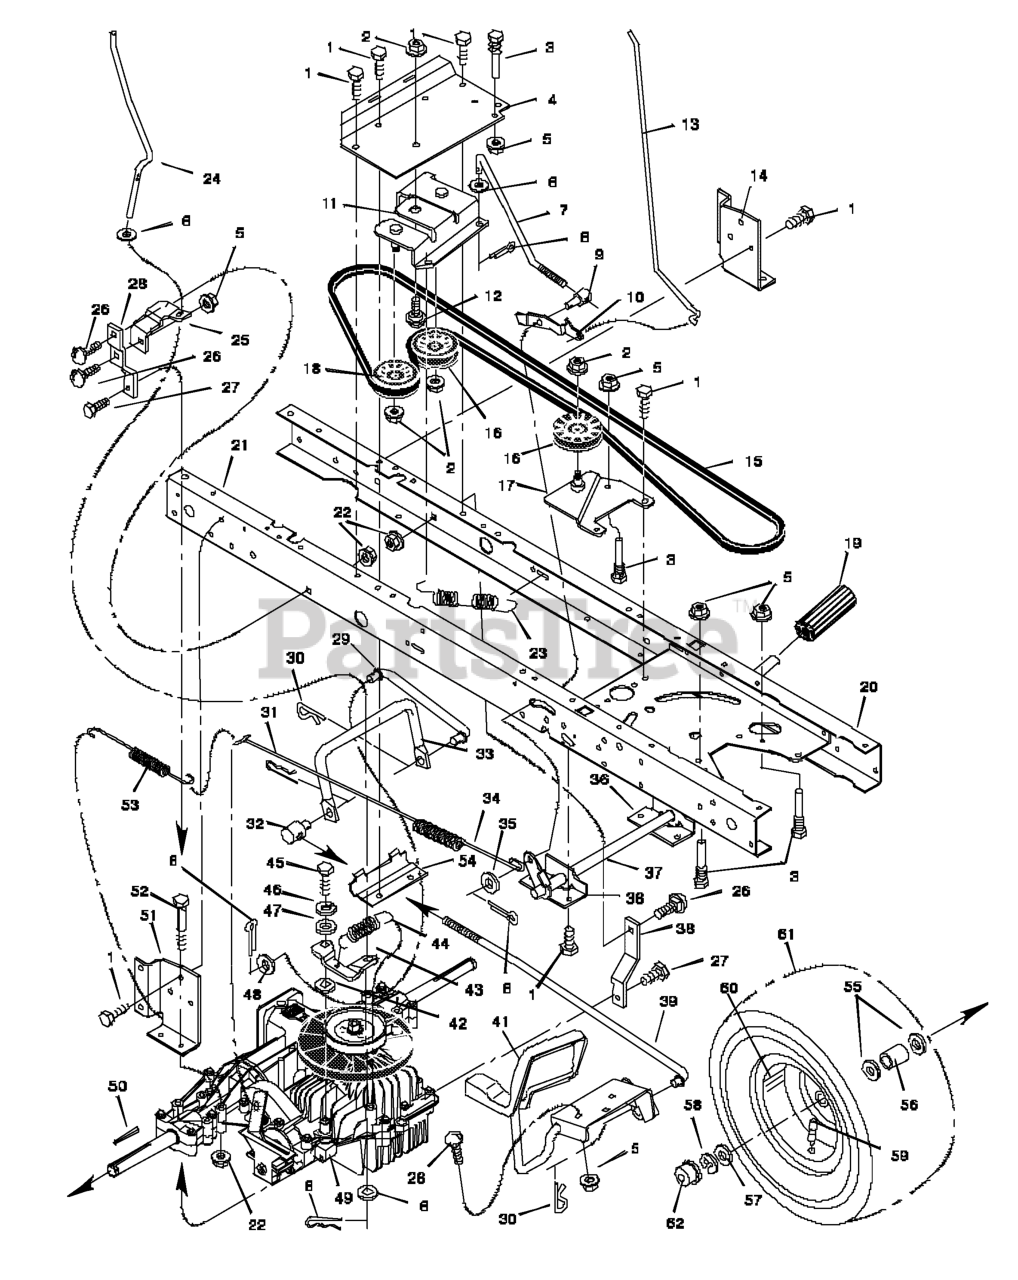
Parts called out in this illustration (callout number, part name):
2	Nut, Flange
3	Guide, Belt
4	Bracket, Idler
5	Locknut
6	Washer
7	Rod, Clutch
8	Pin, Cotter
9	Adjuster
10	Latch, Parking Brake
11	Bracket Assembly, Idler
12	Bolt, Shoulder
13	Rod, Parking Brake
14	Bracket, Transaxle
16	Pulley, Idler
17	Arm Assembly, Idler
18	Pulley, Idler
19	Pedal
20	Frame, Left
21	Frame, Right
22	Nut, Flange
23	Spring, Extension
24	Rod, Disconnect
25	Bracket, Disconnect
26	Bolt, Carriage
28	Strap, Right Torque
29	Rod, Link
30	Pin, Hair
31	Pin, Hair
32	NUT, Adjusting, 1/2-13
33	Rod, Yoke
34	Spring, Extension
35	Washer
36	Bracket, Pivot
37	Lever, Clutch/Brake
38	BRACKET, Torque Strap, LH
39	Rod, Link
41	Pedal, Speed Control
43	Arm, Disconnect
44	Spring
46	Lockwasher
48	Washer
49	Transaxle **
50	Key, Square
51	Bracket, Right Transaxle
52	Bolt
53	Spring, Extension
54	Clamp, Transaxle
56	Spacer
58	E- Ring
59	Valve Stem
60	Wheel & Tire Assembly
61	Tire *
62	Cap, Hub
